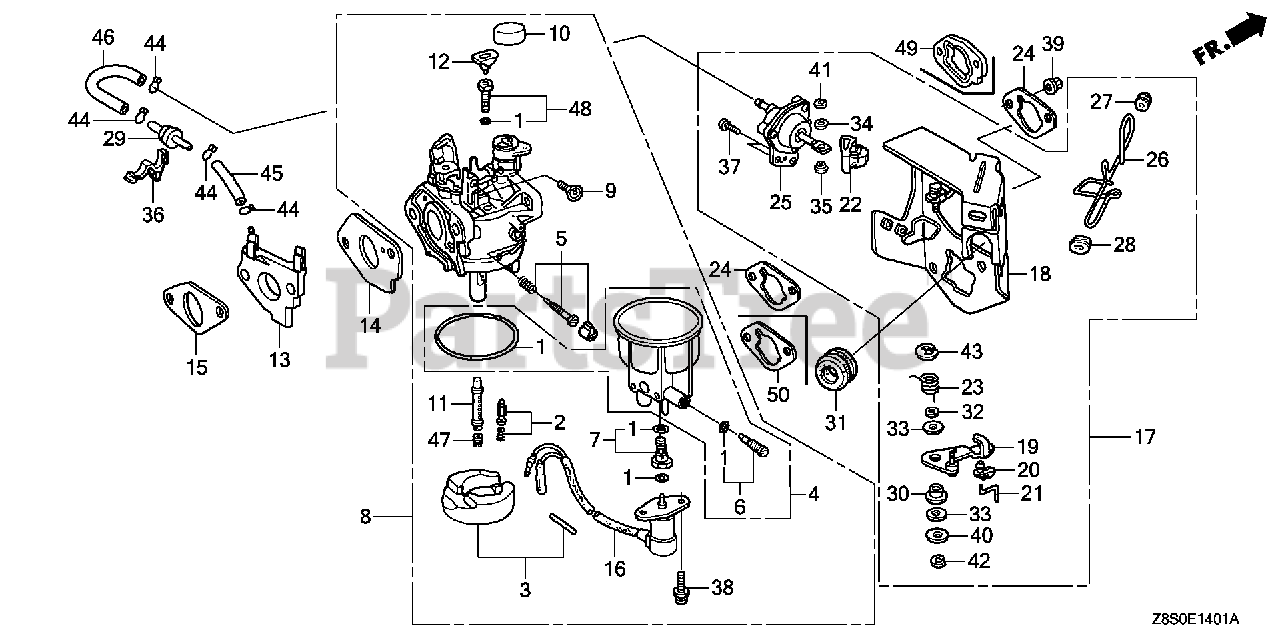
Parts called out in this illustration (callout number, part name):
1	GASKET SET
2	VALVE SET, FLOAT
4	CHAMBER SET, FLOAT
5	SCREW SET, PILOT
6	SCREW SET, DRAIN
8	CARBURETOR ASSY. (BE72R A)
8	CARBURETOR ASSY. (BE72S A)
9	SCREW, THROTTLE STOP
10	CAP, CHOKE DUST
11	NOZZLE, MAIN
12	COLLAR, SETTING
13	INSULATOR, CARBURETOR
14	GASKET, CARBURETOR
15	GASKET, INSULATOR
16	VALVE ASSY., SOLENOID
17	STAY ASSY., MANUAL CHOKE
18	STAY, SOLENOID
19	LEVER, CHOKE
20	JOINT, ROD
21	ROD, CHOKE
22	STOPPER, CHOKE ROD
23	SPRING, MANUAL CHOKE
25	DIAPHRAGM ASSY.
26	ROD, CHOKE CONTROL
27	GROMMET, CHOKE ROD
28	GUIDE, CHOKE ROD
29	VALVE, DASHPOT CHECK
30	BUSH, ARM PIVOT
31	GROMMET, FENDER
32	WASHER, CHOKE LEVER
33	SEAL, CHOKE LEVER
34	WASHER, THRUST (2.7X8)
35	COLLAR, LEVER
36	CLIP, WIRE HARNESS
37	SCREW, PAN (5X12)
38	SCREW-WASHER (5X12)
39	NUT, FLANGE (6MM)
40	WASHER, PLAIN (5MM)
41	E-RING (2MM)
42	E-RING (4MM)
43	E-RING (7MM)
44	CLIP, TUBE (B7)
45	BULK HOSE, VACUUM (3.5X8000) (3.5X65)
46	BULK HOSE, VACUUM (3.5X8000) (3.5X130)
47	JET, MAIN (#78)
47	JET, MAIN (#80)
47	JET, MAIN (#82)
48	JET SET, PILOT (#38)
49	SPACER, CARBURETOR
50	GASKET, AIR CLEANER
